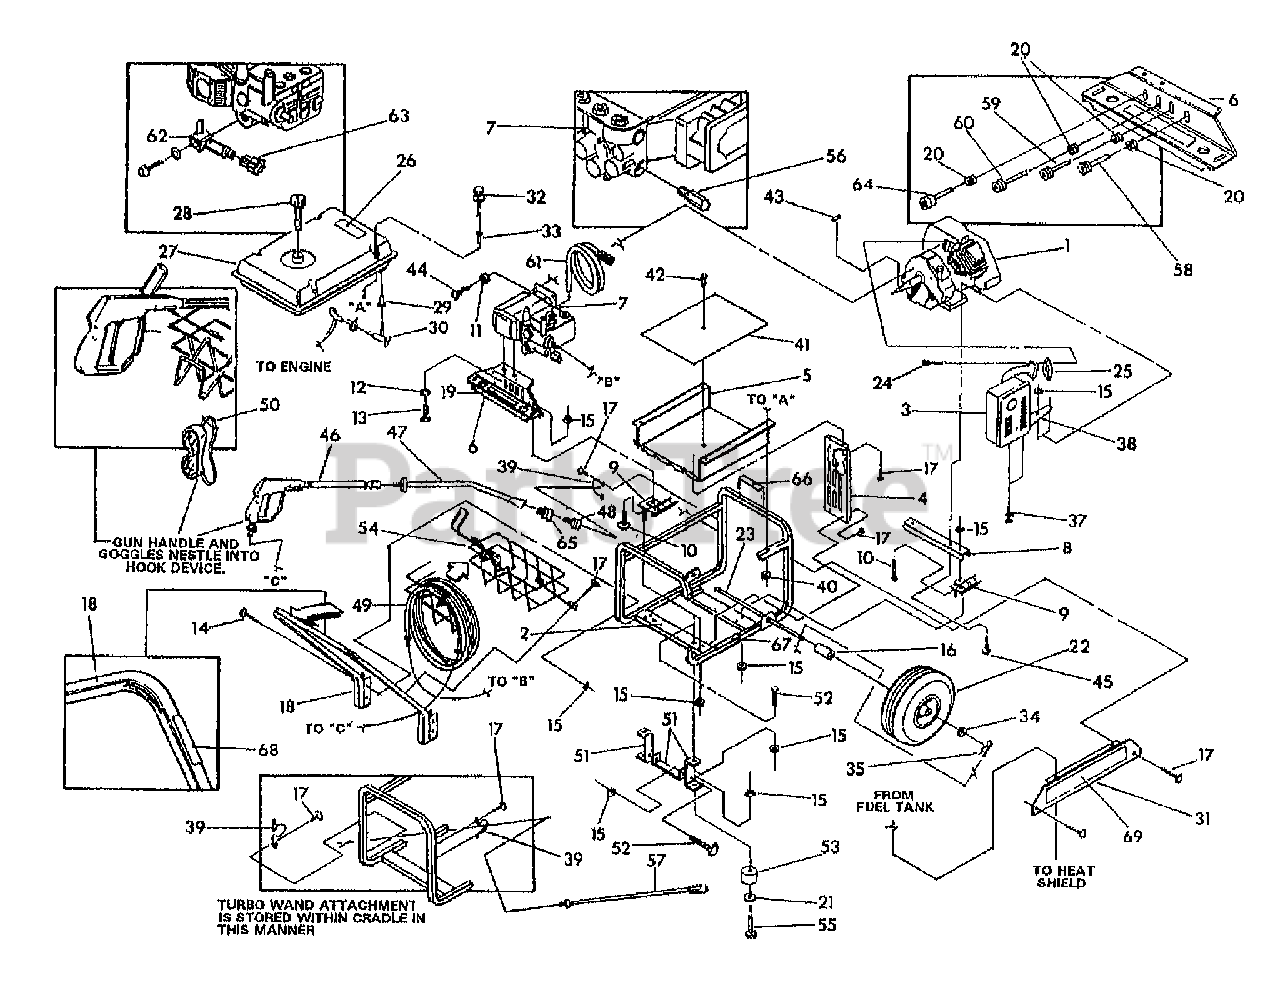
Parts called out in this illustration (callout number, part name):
1	ENGINE-BLOCK GN190
2	CRADLE-XL (4000W GEN)
3	MUFFLER
4	HEATSHIELD-MUFFLER
5	SHIELD-HEAT TANK (PRES.WASHR)
6	BRKT-PUMP MOUNT
7	PUMP-XTV 2200 SERIES (TB PRS W
8	SUPPORT-ENGINE
9	MOUNT-VIBRATION 45 DEG.
10	SCR M8-1.25X20MM
11	WASHER-CONICAL 5/16
12	WASHER-LK M8
13	SCR-CAP M8-1.25X16MM
14	SCR-CAP M8-1.25X45MM
15	NUT-HF/LK M8-1.25
16	SPACER-WHEEL (PRS WSHR)
17	SCR-CAP M10-16 SELF DRILL
18	HANDLE (6000W GENERATOR)
19	DECAL-NOZZLE (PRS WSHR)
20	GROMMET-NOZZLE (PRS WSHR)
21	WASHER-M8 VIBRATION MOUNT
22	ASSM-WHEEL (PRES.WSHR)
23	AXLE (4000W GENERATOR)
24	SCR-SKT HD M8-1.25X20 LONG (GE
25	GASKET-EXHAUST
26	DECAL-DANGER
27	TANK-FUEL
28	GAUGE-FUEL
29	BUSHING-PLASTIC TANK (PRS WSHR
30	VALVE-FUEL TANK (PRES.WSHR)
31	PANEL-SIDE DECAL
32	SCR-HH M6-1.00X60MM LONG (GEN)
33	GROMMET-TANK
34	WASHER-WHEEL (GENERATOR)
35	PIN-RETAINING
37	SCR M6-1.0X12MM W/LK WSHR
38	BRACKET-MUFFLER
39	HOLDER-REAR GUN
40	NUT-HF/LK M6 FLANGE
41	INSULATION-1/4" THICK #2
42	CLIP-INSULATION
43	KEY-.188 SQ X .25
44	SCR-HH 5/16-24X.75
45	SCR-PHP M8X35MM
46	GUN-MASTER CONTRACTOR
47	EXTENSION-WAND M.C.
48	NOZZLE-CHEMICAL INJECTOR
49	ASSM-HOSE 3/8" ID (50FT)
50	GOGGLES
51	BRKT-UNIT SUPPORT
52	SCR-HH M8-1.25X20 MM
53	MOUNT-VIBRATION
54	BASKET-WIRE (PRES.WASHER)
55	SCR-HH M8-1.25X30MM
56	VALVE-THERMAL RELIEF (PRS WSHR
57	UD ASSM-TURBO WAND
58	NOZZLE-QUICK CON 00045 RED
59	NOZZLE-QUICK CON 15045 YELLOW
60	NOZZLE-QUICK CON 25045 GREEN
61	ASSM-FILTER&INJECTOR TUBE
62	NECK-ALUMINUM PUMP (PRS WSHR)
63	CONNECTOR-(BRASS) GARDEN HOSE
64	NOZZLE-QUICK CON 40045 WHITE
65	ADAPTOR-QUICK CONNECT (PRS WSH
66	DECAL-PLACE HAND HERE
67	DECAL-WARNING HOT SURFACE
68	DECAL-CAUTION SPRAYGUN (PRS WS
69	DECAL-LOGO T/B PRS WASHER
